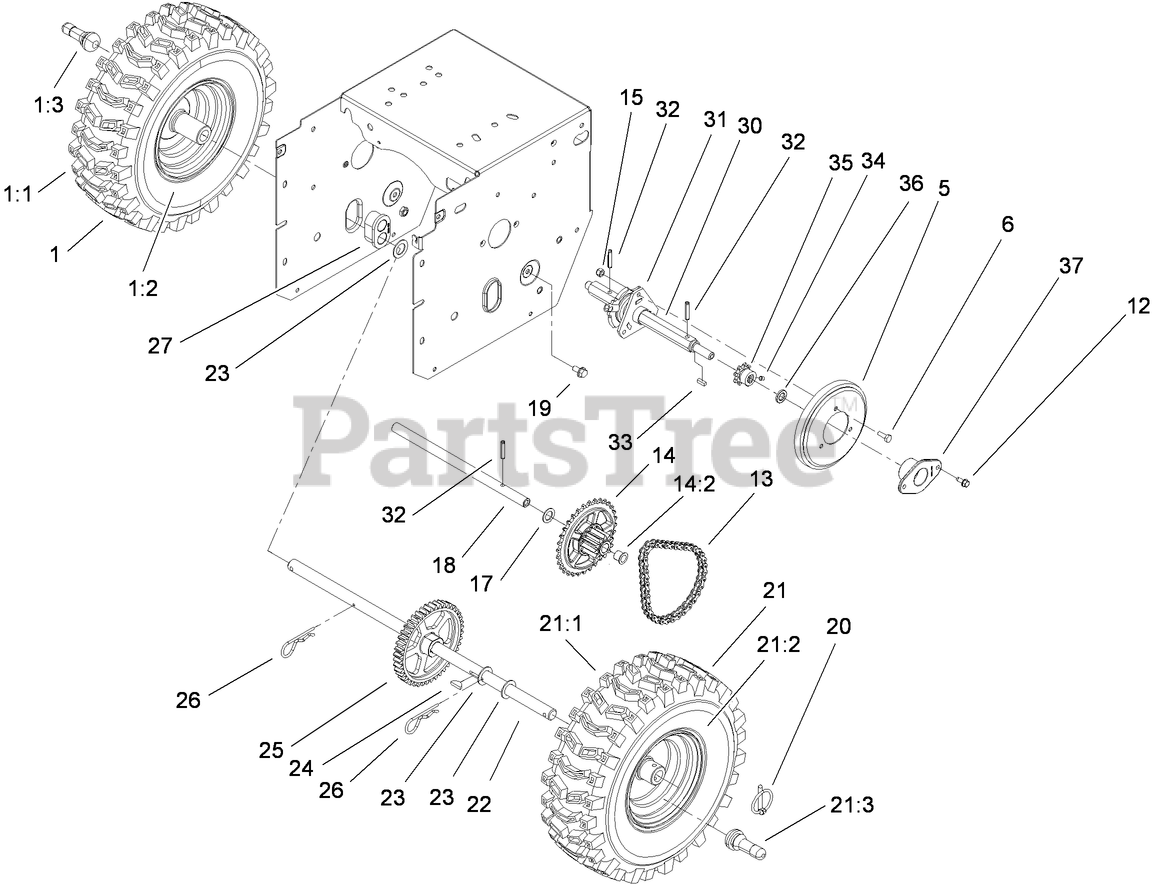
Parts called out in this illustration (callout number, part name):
1	Loose Parts Package
1:2	RIM-TIRE
6	SCREW-HH
12	SCREW-HWH
13	CHAIN-ROLLER
13	LINK-CONNECTING
14	SPROCKET ASM
14:2	BUSHING-FLANGE
15	NUT-LOCK, NI
17	WASHER-FLAT
18	SHAFT-INTERMEDIATE
19	SCREW-HWHTF
20	KLIK PIN ASM
21	Loose Parts Package
21:2	RIM-TIRE
22	SHAFT-AXLE
23	WASHER-THRUST
24	KEY-WOODRUFF
25	GEAR-AXLE, 44 TOOTH
26	PIN-HAIR
27	BEARING-AXLE
30	SHAFT-HEX
31	TRUNNION-HEX
32	PIN-ROLL, SLOTTED
33	KEY-SQUARE
34	SCREW-HSH
35	SPROCKET-8 TOOTH
36	SPACER-BUSHING
37	RETAINER-BEARING
